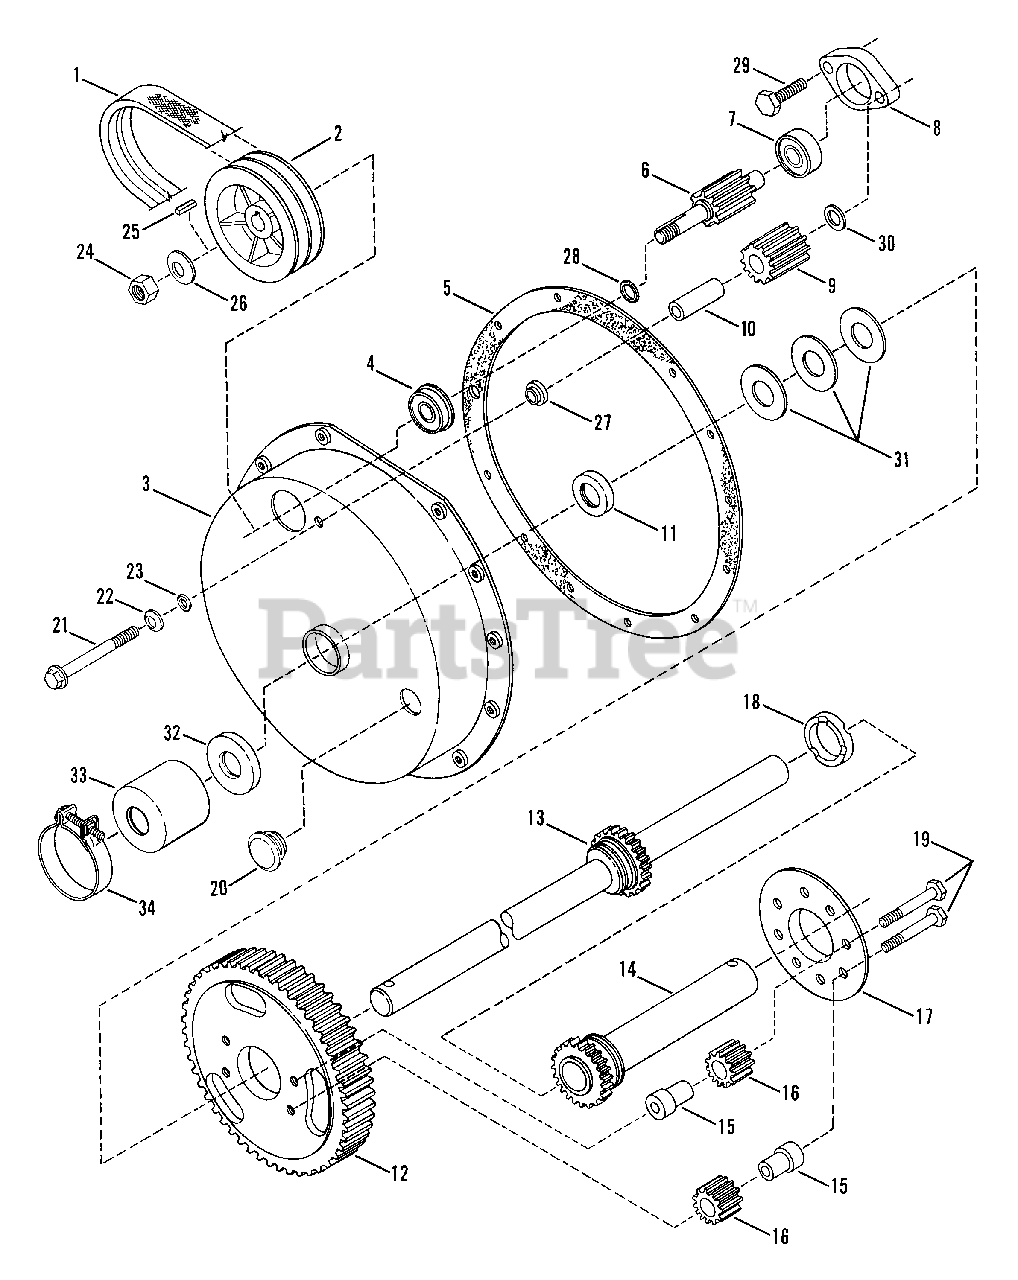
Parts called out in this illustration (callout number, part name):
1	BELT, Wheel Drive
2	PULLEY, Wheel Drive Belt
3	COVER, Differential
4	BEARING
5	GASKET, Differential Cover
6	PINION GEAR & SHAFT
7	BEARING
8	HOLDER, Bearing
9	GEAR, 11 Teeth, 10 Pitch
11	SEAL, Differential
12	GEAR, 63 Teeth, 10 Pitch
13	AXLE, Long
14	AXLE, Short
15	SPACER, Pinion
16	PINION GEAR, Differential
17	PLATE, Differential
18	SPACER, Differential (1.25" ID x .425 Wide)
19	SCREW, 5/16-24 x 1-5/8" Hex Head Cap, Special Lock
20	PLUG, 3/4"
21	SCREW, 5/16-24 x 2-1/2" Hex Head Cap
22	WASHER, Belleville
23	O-RING, 5/16"
24	NUT, 7/16-20 Hex, Top-Lock
25	KEY, Square, 1/8 x 1/2" L.
26	WASHER, Belleville, 7/16"
28	O-RING, 15/32"
29	SCREW, 5/16-24 x 1" Hex Head Cap
30	WASHER, Shim, 5/16"
31	WASHER, Thrust
32	SEAL, 3/4"
33	CAP
34	CLAMP, 1-5/8"
